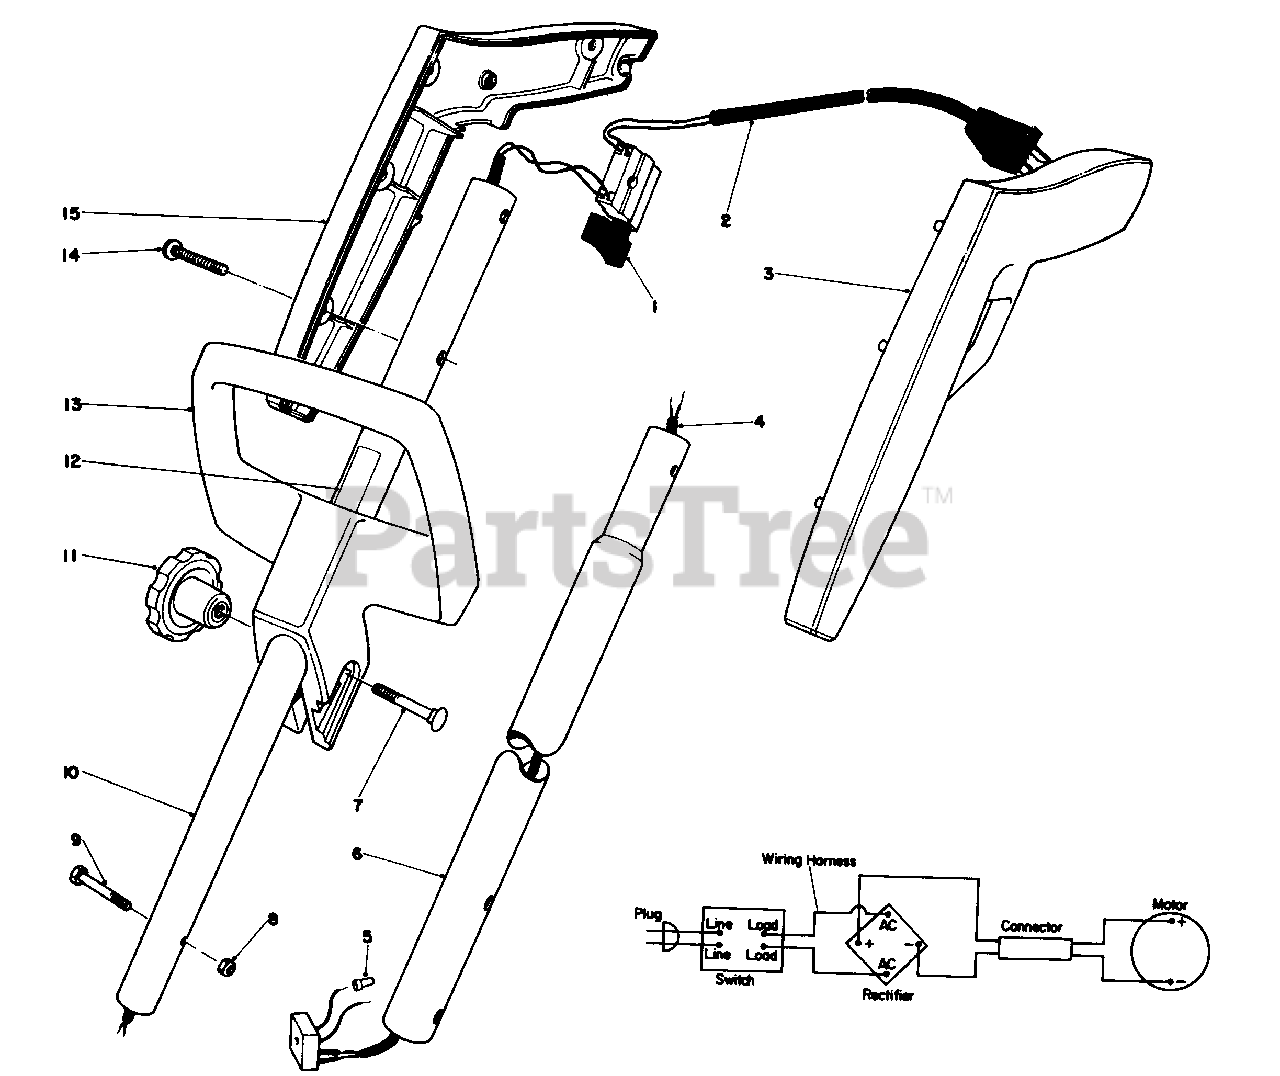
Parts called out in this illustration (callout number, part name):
2	Power Cord
3	Hand Grip L.H.
4	Wiring Harness w/Rectifier
5	Wire Connectors
6	Tube-Lower
7	Carriage Bolt
9	Machine Screw
10	Tube-Upper
12	Decal-Caution
13	Adjustable Handle
14	Screw
15	Hand Grip R.H.
